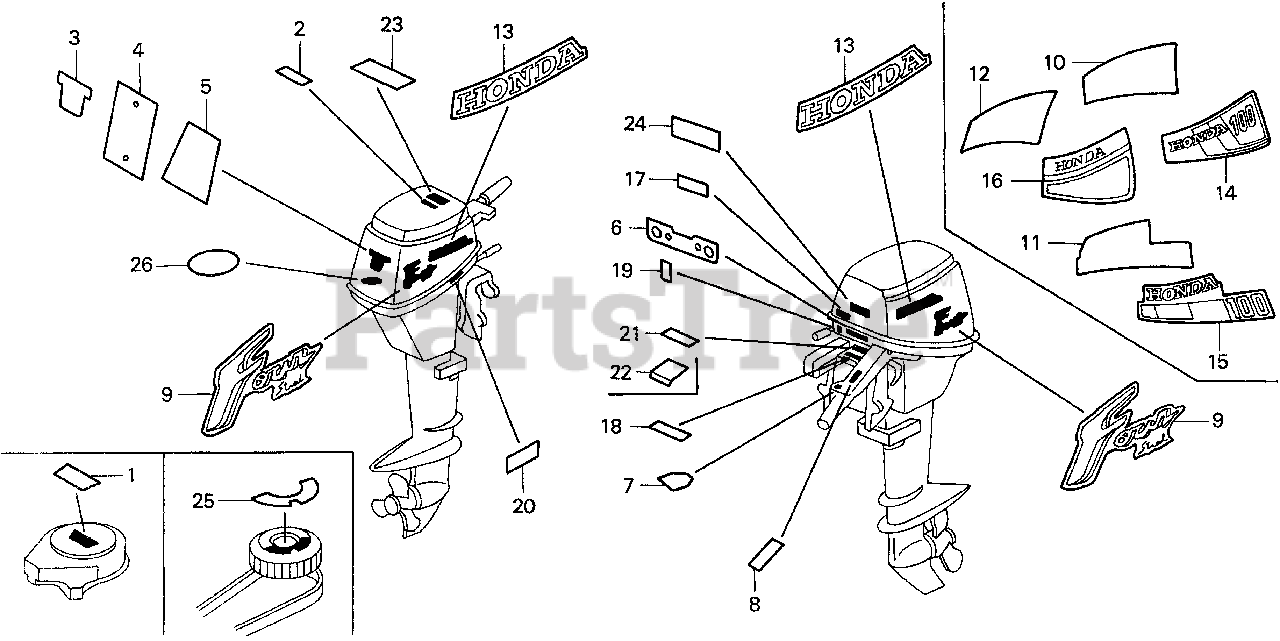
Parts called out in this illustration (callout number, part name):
2	MARK, INSTRUCTION
4	EMBLEM, RR. (NOT AVAILABLE)
6	LABEL, INDICATION (NOT AVAILABLE)
7	MARK, HANDLE FOREIGN (NOT AVAILABLE)
11	EMBLEM, R. SIDE COVER (NOT AVAILABLE)
15	EMBLEM, L. SIDE COVER
19	MARK, CHANGE
20	LABEL, OIL FILLER POSITION
22	PLATE, SETTING CAUTION
23	MARK, STARTER CAUTION (NOT AVAILABLE)
24	MARK, FR. (NOT AVAILABLE)
